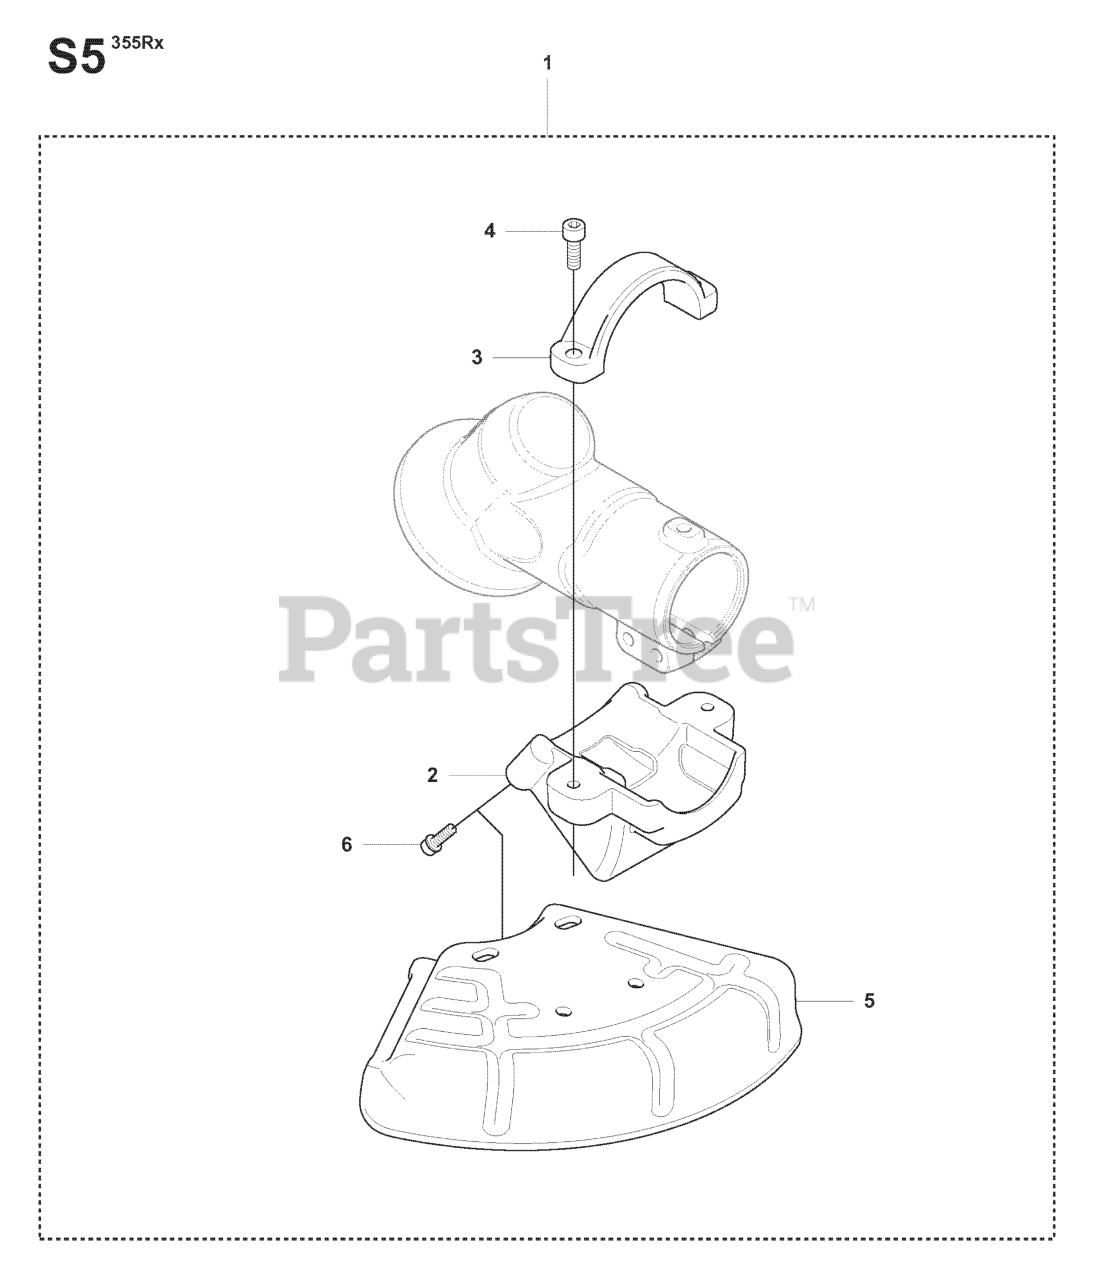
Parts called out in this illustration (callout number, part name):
2	BLADE GUARD SAW
5	BLADE GUARD SAW
6	SCREW IHSCFM
